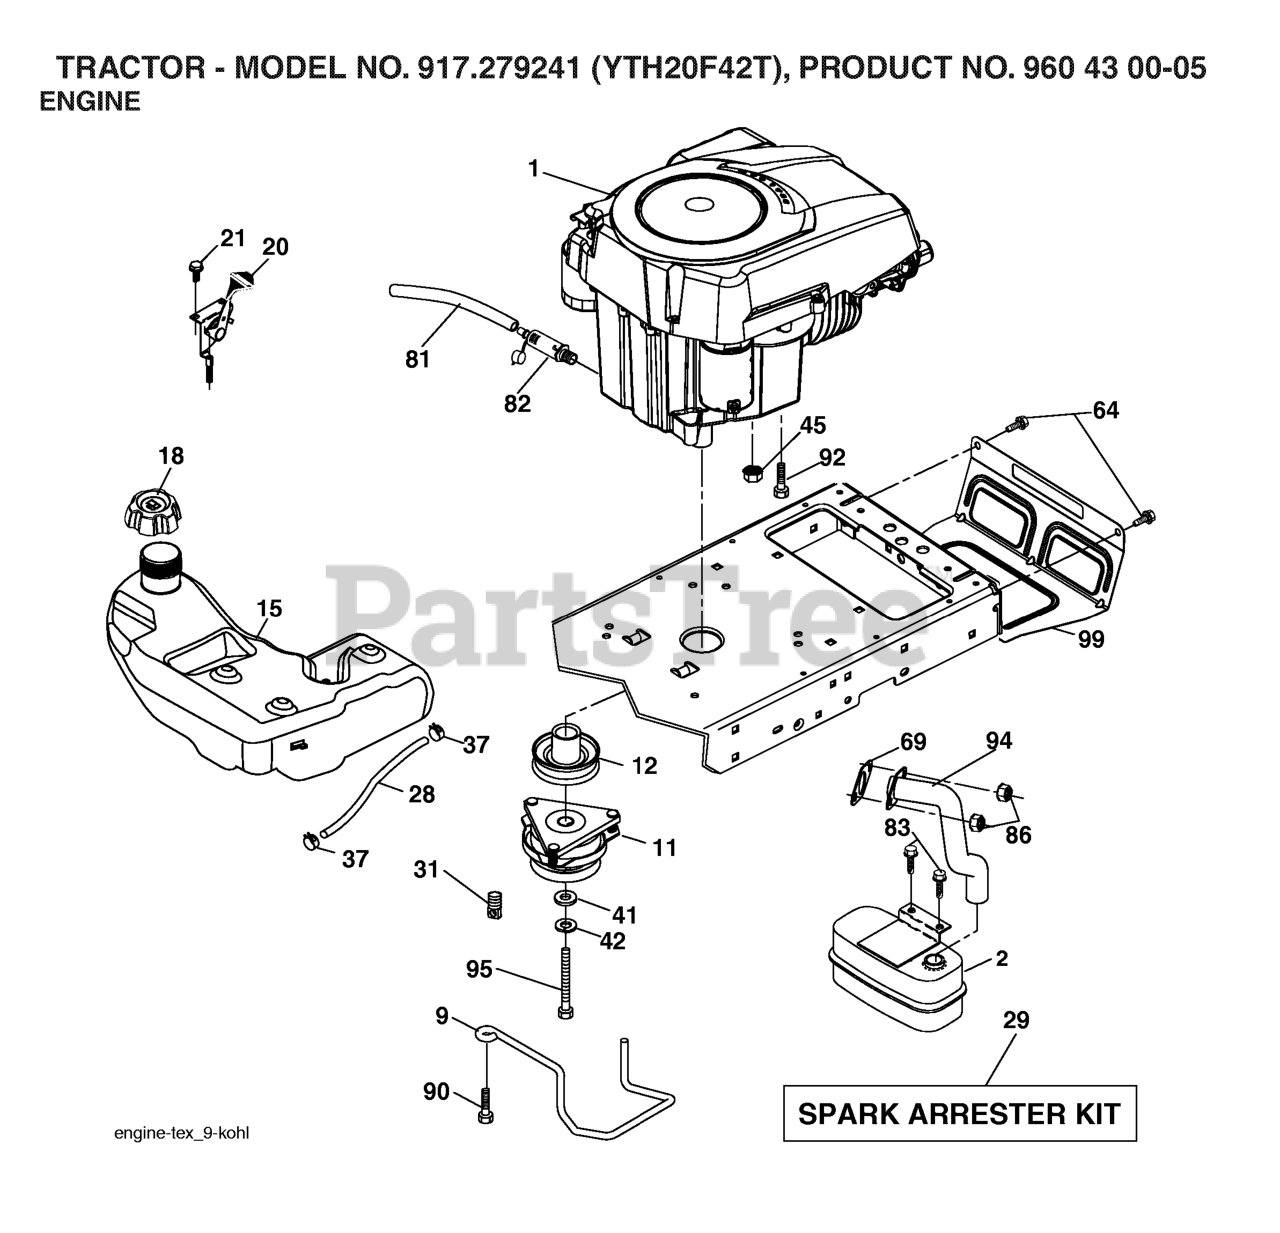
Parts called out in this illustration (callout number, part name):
2	MUFFLER.SINGLE.CYL.KOHL/B&S
9	KEEPER.BELT.ENGINE.4.2
11	RB.CLUTCH.OGURA.4.4.PD
12	PULLEY.ENGINE.TUFFTORQ
15	TANK.FUEL.4GAL
18	CAP.FUEL.TANK.3"GREY
20	CONTROL.TH/CK.COBRA.KO
21	SCREW
28	LINE.FUEL.64"REAR.EMIS
29	KIT.SPARK ARRESTOR 794945 B&S
31	DECAL BTRY SYMBOLS
37	HOSE CLAMP
42	LOCKWASHER
45	NUT
64	SCREW, 3/8-16X3/4
69	GASKET.EXHAUST.KOHLER
81	TUBE, DRAIN OIL ASM.
82	PLUG DRAIN OIL EASY
83	BOLT.5/16-18UNCX3/4 W/SEMS.BLK
86	NUT.HEX.FLANGE.TOPLOCK
90	SCREW 3/8-16X1
92	SCREW 3/8-16X1
94	RP.TUBE.EXHAUST.KOHL.COURAGE
95	BOLT HEX 7/16-20X4-1/4"
99	SHIELD.BROWNING/DEBRIS
